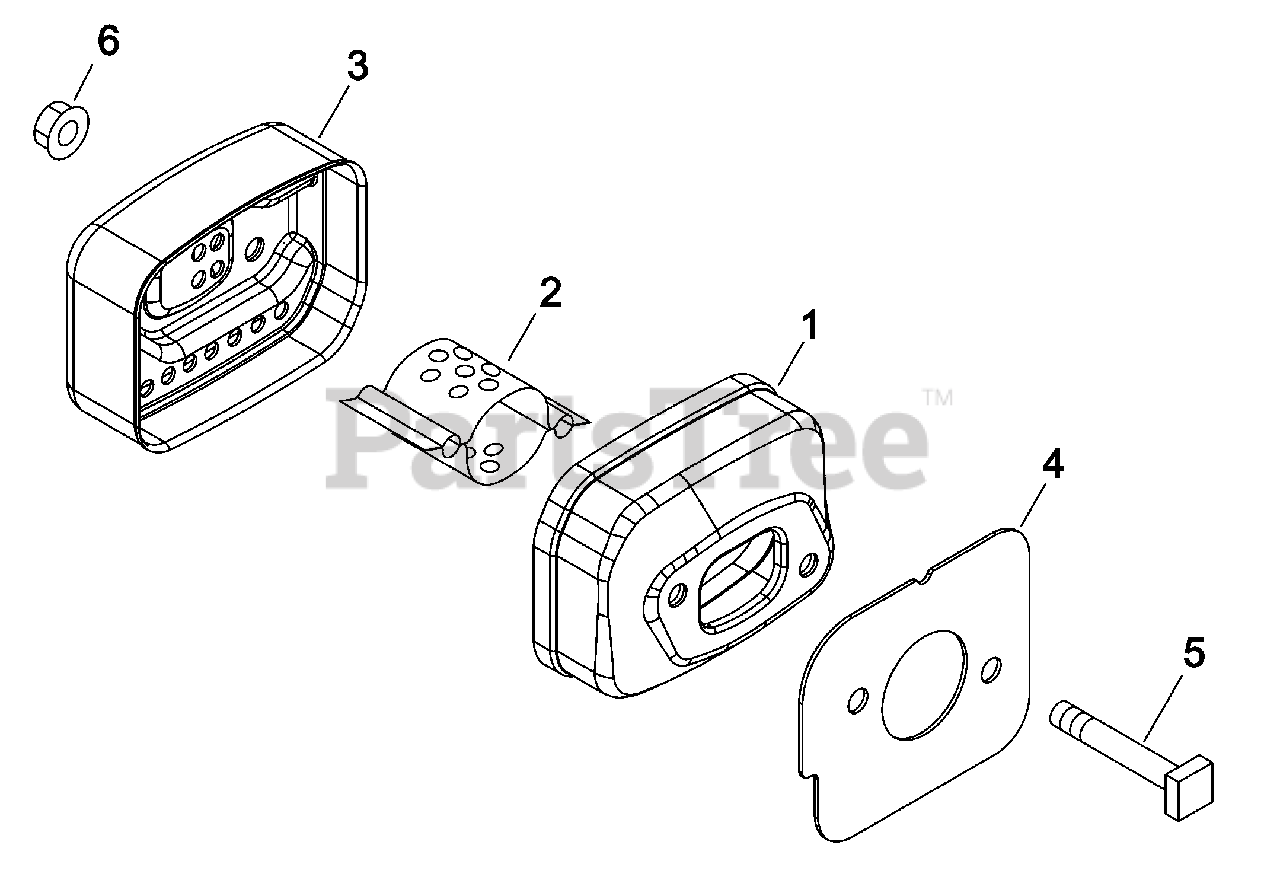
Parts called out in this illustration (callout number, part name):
2	PLATE, MUFFLER
3	COVER, MUFFLER
4	GASKET, EXHAUST
6	NUT, FLANGE M5
